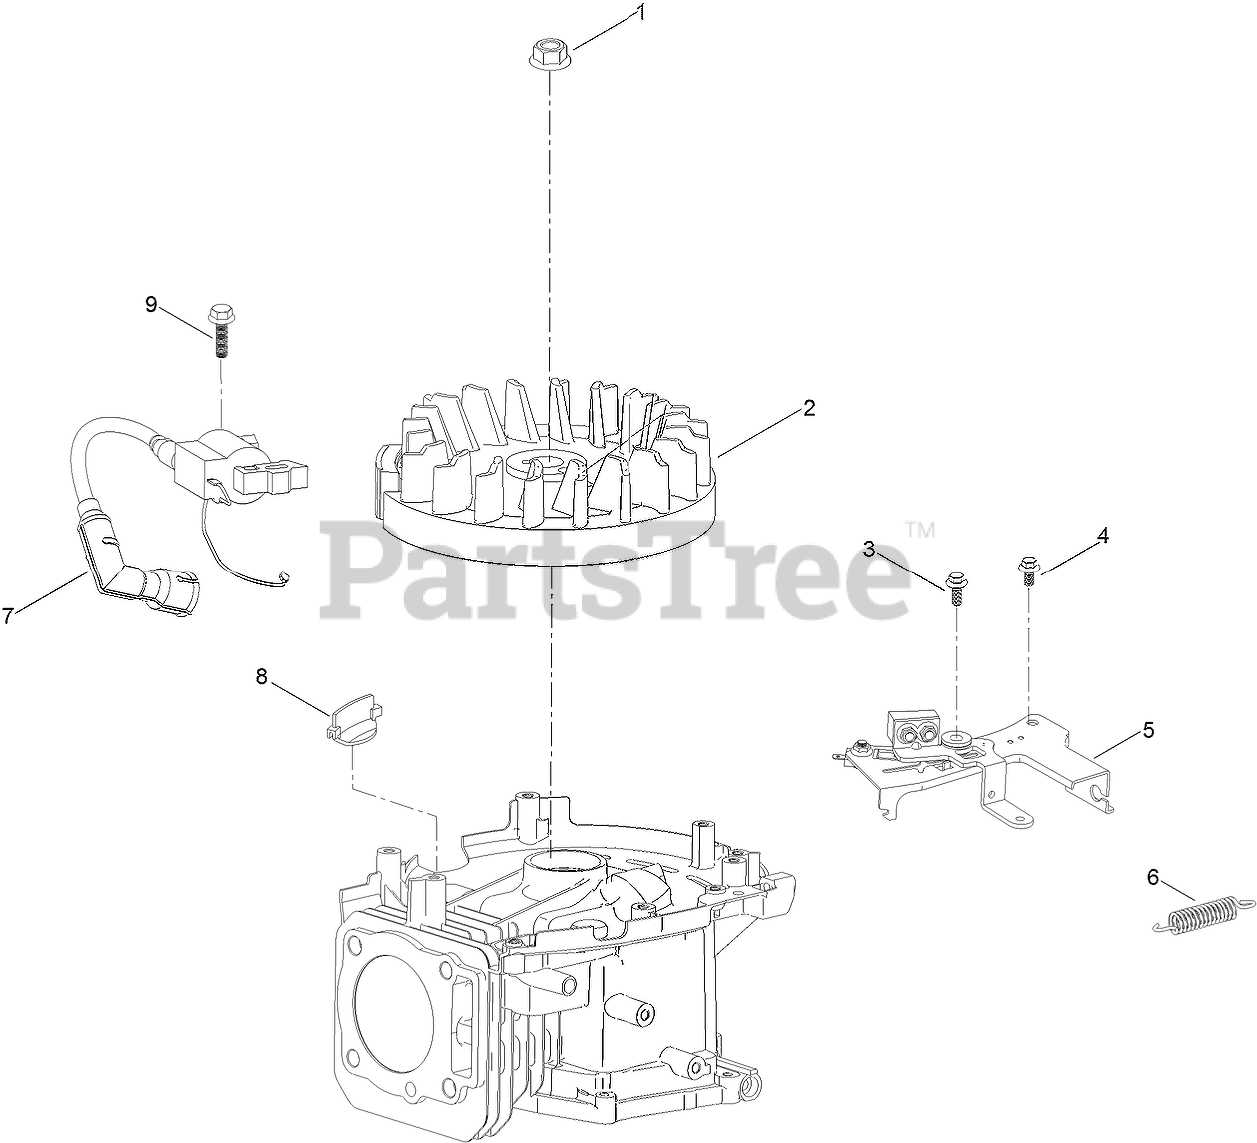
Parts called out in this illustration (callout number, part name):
1	NUT-FLANGE
2	FLYWHEEL
3	BOLT-FLANGE
4	SCREW-HHF
5	BRAKE ASM
6	SPRING-BRAKE
7	IGNITION COIL ASM
8	GUARD-FLYWHEEL
9	SCREW-HHF
